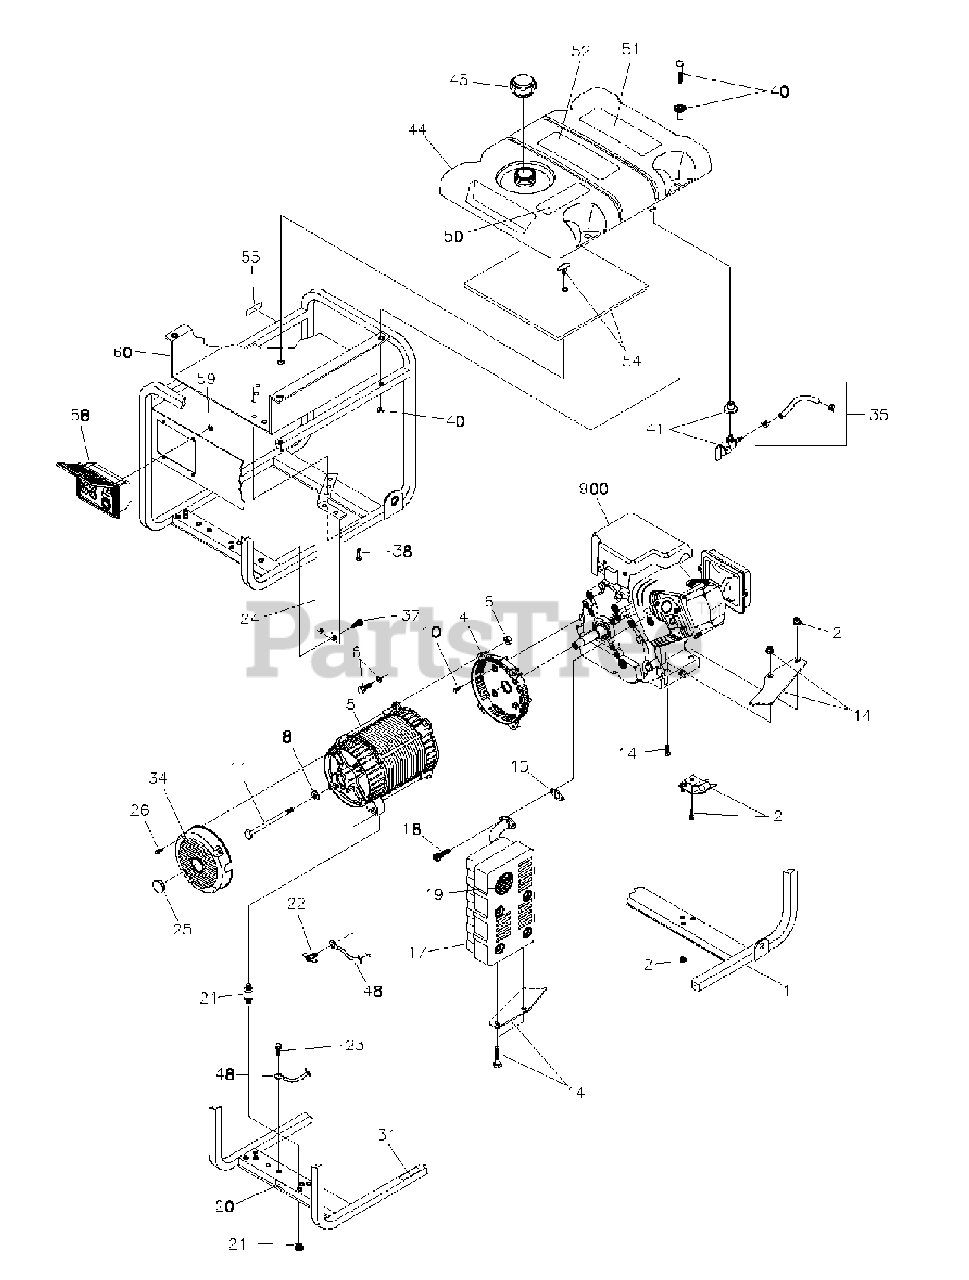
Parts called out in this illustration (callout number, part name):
2	KIT, Vibration Mount, 45°
4	HOUSING, Engine Adapter
5	ALTERNATOR ASSEMBLY
6	KIT,Hardware Mounting Adapter
8	WASHER, Flat M8.4 x 22.2 x 3
10	SBHCS, 3/8-16 x 1.0 Lg.
11	HHCS,5/16-24 x 7-7/16
14	KIT,Muffler Bracket w/ Hardware
15	GASKET, Exhaust
18	SCREW, 5/16 - 18 x 3/4"
19	SCREEN, Spark Arrest
20	DECAL, Ground, Green
21	KIT, Vibration, Mount
22	SCREW, Wing M6 - 1.0 x 16
23	SCREW, 10-16 x 3/4 Self Drill
24	SHIELD, Heat
26	SCREW, M5-0.8 x 10,Taptite
31	DECAL,Hot Muffler
34	COVER, Bearing Carrier with Cap
35	KIT, Fuel Hose w/ Clamps
37	HHCS, 12 - 14 x 7/8" Self Driller
38	SCREW, 10-24 x 1/2 Crimptite
40	KIT, Hardware Tank Fuel (Includes Qty. of 4)
41	KIT, Valve, Fuel Tank
44	ASSY, Tank, Fuel (Includes Items 41, 50, 51 & 52)
45	CAP,Fuel Gauge
48	WIRE, Ground
50	DECAL, Instruction, Fuel Level
51	DECAL, Danger
52	DECAL, Operating Instructions
54	KIT, Insulation with Clip
55	DECAL,Fuel Shut-off
58	ASSY, Control Panel (see Control Panel group)
60	SHIELD, Heat
